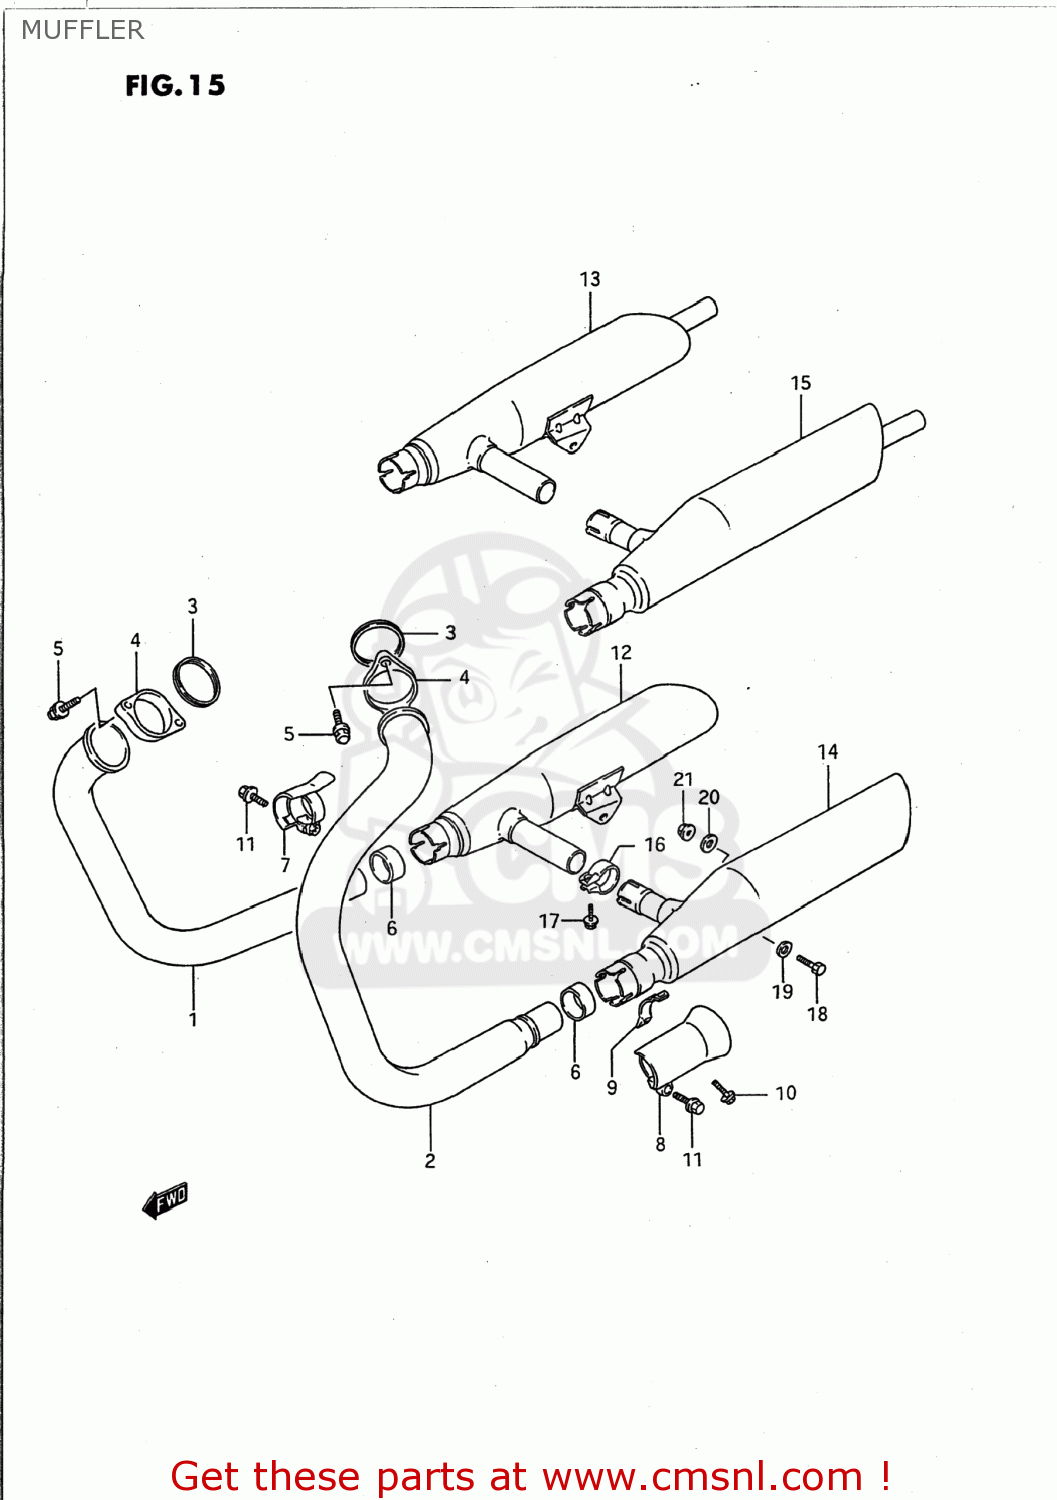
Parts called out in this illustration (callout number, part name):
1	PIPE,EXHAUST R
2	PIPE,EXHAUST
3	GASKET,EXHAUST PIPE (NAS)
3A	BOLT
4	CLAMP,EXHAUST PIPE
5	BOLT(8X35)
6	CONNECTOR,MUFFLER
7	CLAMP,CONNECTOR,R
8	CLAMP,CONNECTOR,L
9	CLAMP,MUFFLER COVER
10	BOLT
11	BOLT
12	BODY,MUFFLER
13	BODY,MUFFLER
14	CLAMP,EXHAUST COUPLER
15	BOLT
16	BOLT
17	WASHER
17A	BOLT
18	WASHER
19	NUT
